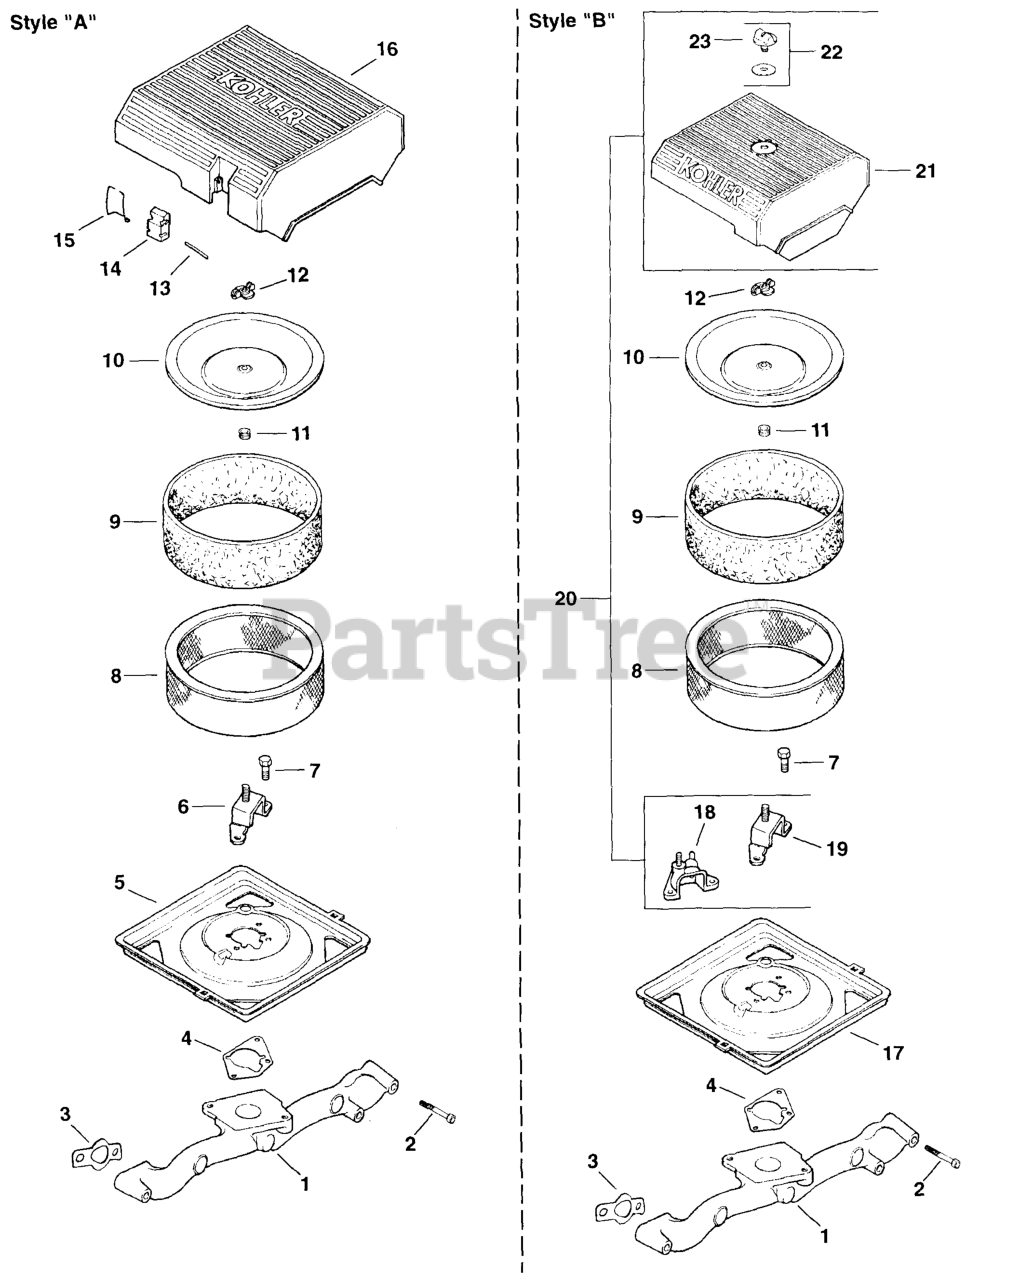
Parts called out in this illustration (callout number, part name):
1	Manifold, Intake
2	Screw, Hex. Flange M6x1.0x55
3	Gasket, Intake Manifold
4	Gasket, Air Cleaner Base
5	Base, Air Cleaner
7	Screw, Hex. Flange M6x1.0x16
8	Element, Air Cleaner
9	Element, Precleaner
10	Cover, Inner Air Cleaner
11	Seal, Inner - Air Cleaner
12	Nut, Wing
18	Cup, Fuel Spitback
19	Bracket, Air Cleaner
20	Kit, Air Cleaner Cover
21	Cover, Air Cleaner
22	Kit, Air Cleaner Knob W/Gasket
23	Knob, Air Cleaner Cover
